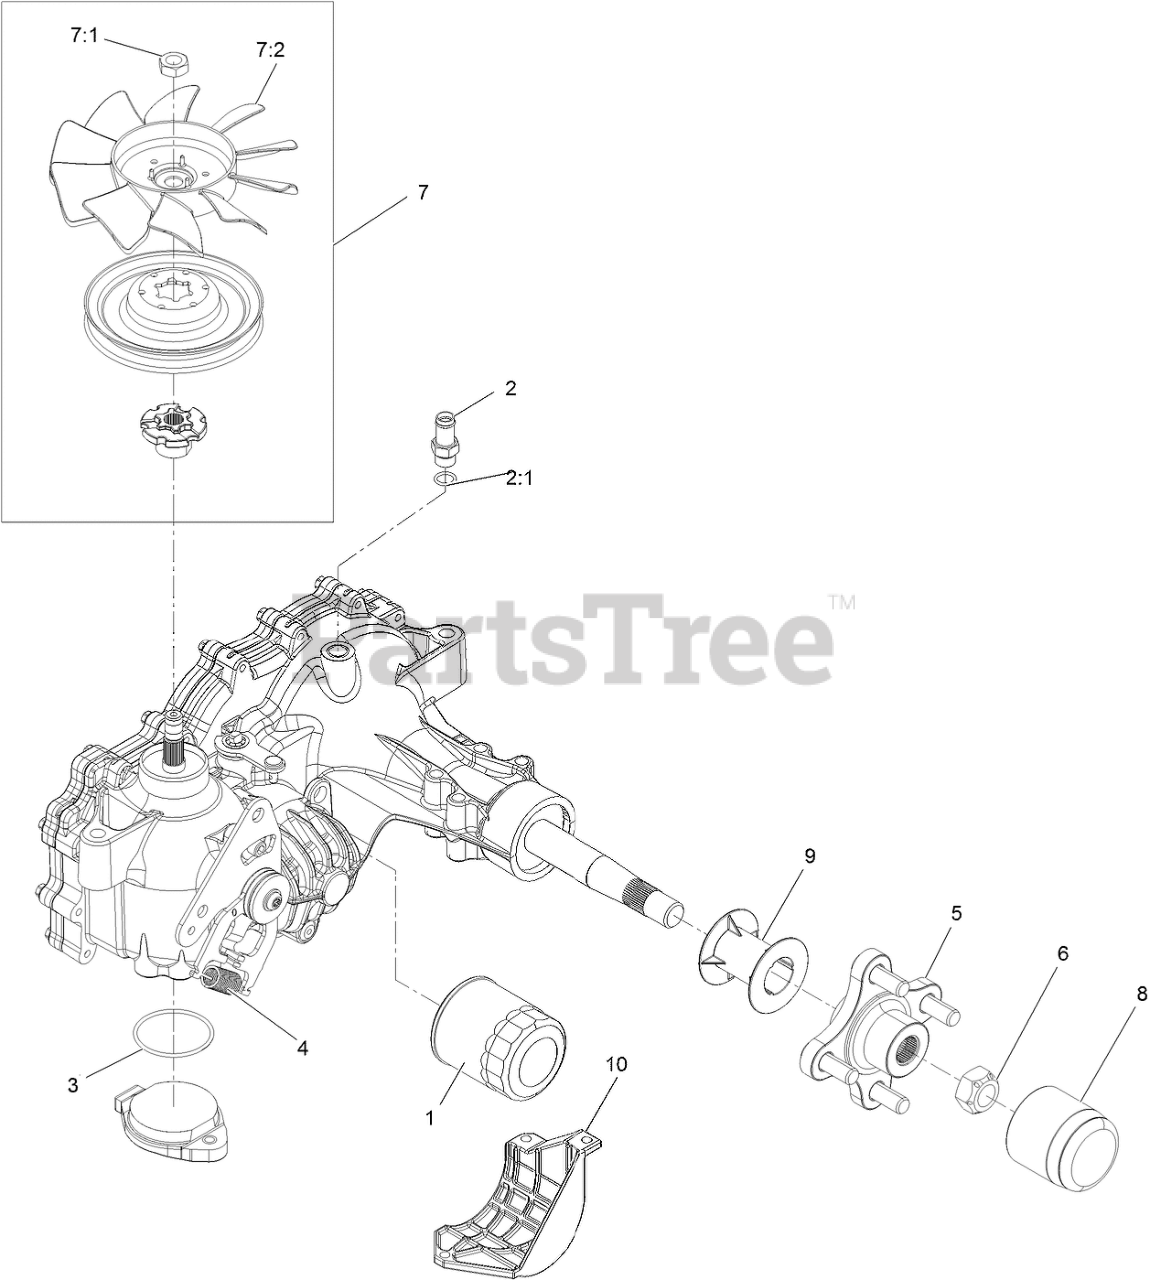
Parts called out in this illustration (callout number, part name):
1	ELEMENT-OIL FILTER, HYD
2	ADAPTER-STRAIGHT
2:1	O-RING
3	O RING-SEAL
4	SPRING-EXTENSION
5	HUB-OFFSET
6	NUT-HUB
7	Fan And Pulley Kit
8	CAP-AXLE, LONG
9	TUBE-AXLE
10	GUARD-FILTER, RH
